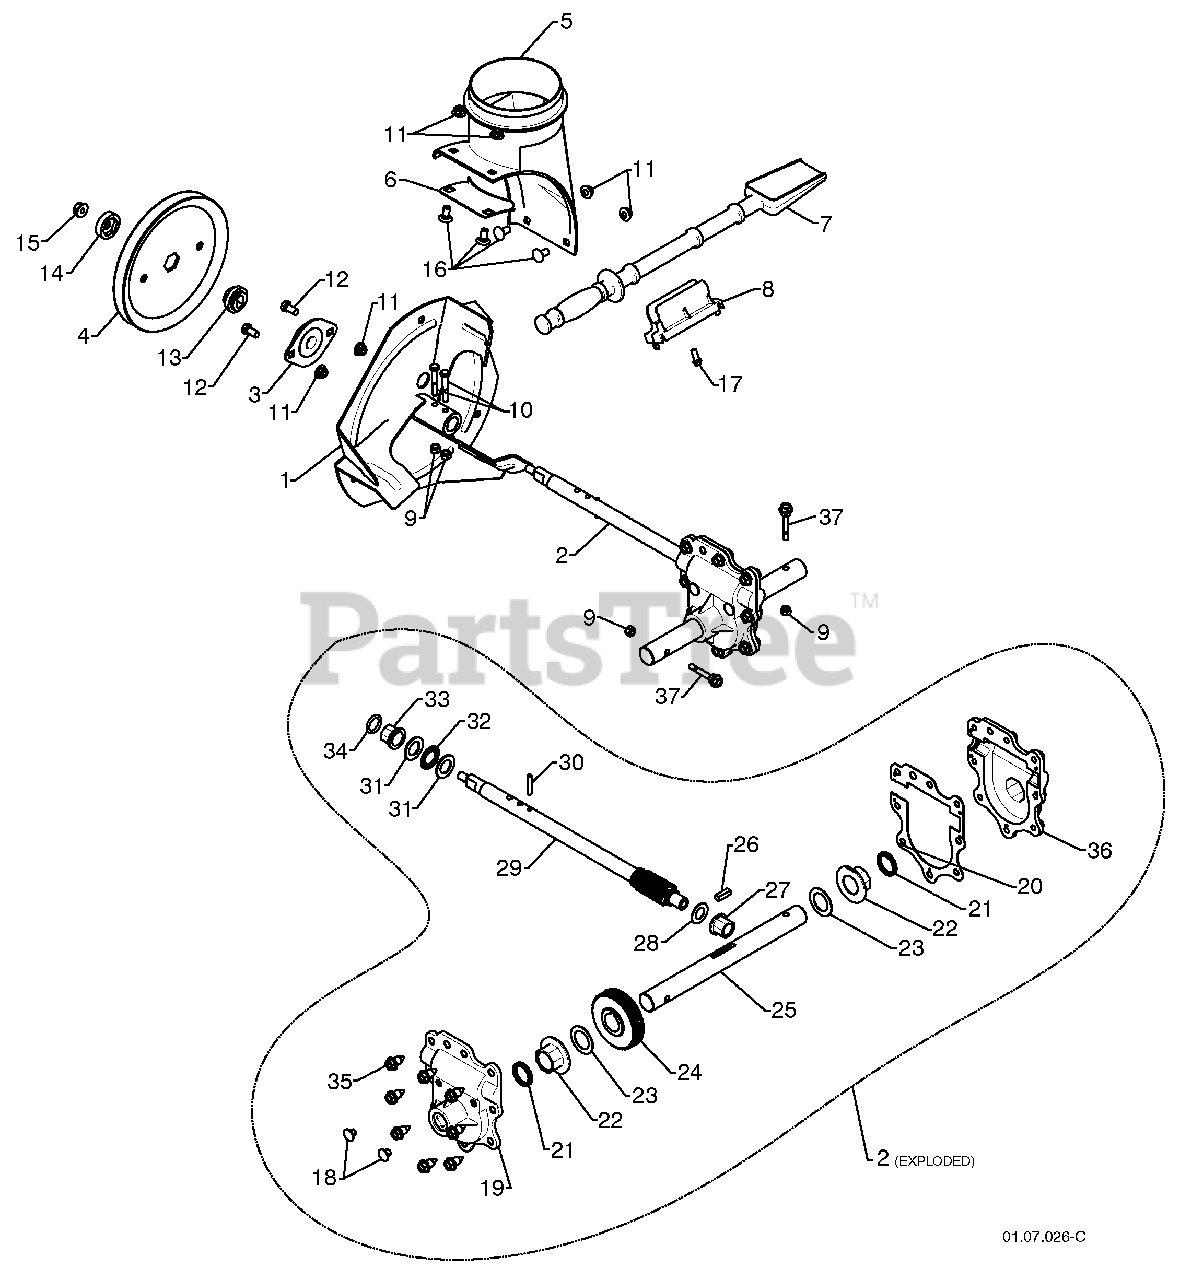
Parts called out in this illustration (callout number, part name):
1	IMPELLER
2	GEARBOX ASSEMBLY
3	BEARING
4	IMPELLER PULLEY
5	DISCHARGE BASE
6	CORNER BRACKET
7	CLEAN OUT TOOL
8	TOOL CLIP
9	NUT 1/4-20
10	SCREW 1/4-20 X .625
11	NUT 5/16-18
12	SCREW 5/16-18 X .625
13	IMPELLER HUB
14	IMPELLER SLEEVE
15	NUT 3/8-16
16	CARRIAGE BOLT
17	SCREW 13-16 X .625
19	GEARBOX COVER RH
20	GASKET
22	BEARING
23	THRUST WASHER 1.00
25	AUGER SHAFT
26	SQUARE KEY
28	THRUST WASHER
29	IMPELLER SHAFT
31	THRUST WASHER
32	THRUST BEARING
34	O-RING
35	SCREW 5/16-18 X .750
36	GEARBOX COVER LH
37	SHEAR BOLT
